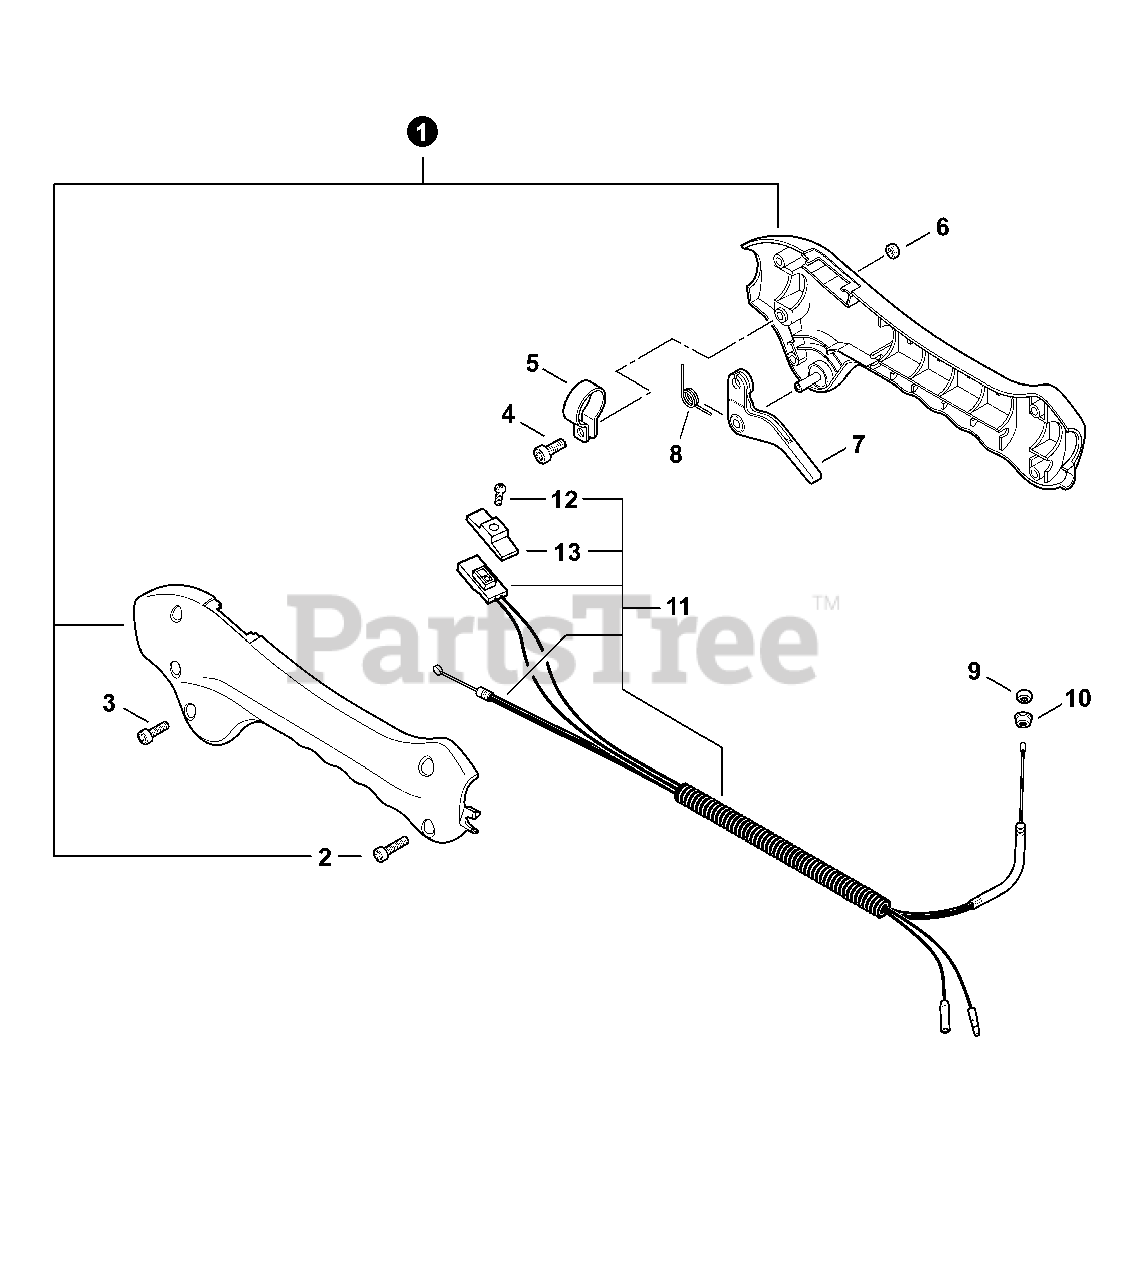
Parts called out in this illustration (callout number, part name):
1	CONTROL HANDLE KIT
2	BOLT, TORX 4×16
3	BOLT, TORX 4×12
4	BOLT, TORX 5×12
6	NUT M5
7	TRIGGER, THROTTLE
8	SPRING, TORSION
10	NUT, FLANGE M6
11	CABLE ASSY, CONTROL
12	SCREW 3×10
13	KNOB, SWITCH - ORANGE
